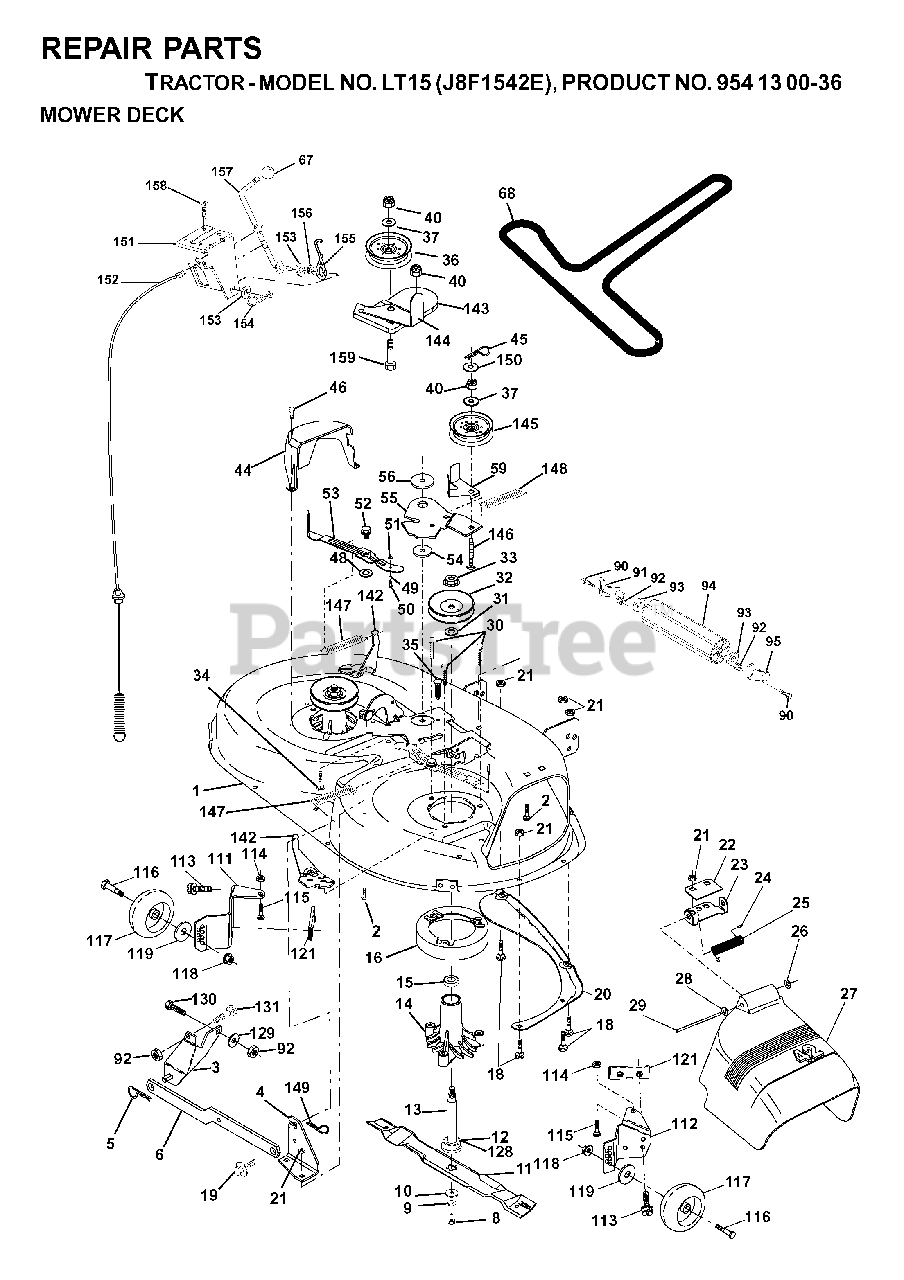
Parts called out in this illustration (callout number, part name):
1	42" DECK KIT
2	BOLT
3	BRKT ASM SWAY BAR
4	BRACKET SWAY BAR 42" DECK
5	RETAINER-SPRNG RB
6	REAR SUSP ARM
8	BLADE BOLT
9	LOCKWASHER
10	WASHER.BLADE
12	BEARING
13	SHAFT ASM VENT
14	HSG MANDREL
16	STRIPPER
18	BOLT
19	BOLT SHD 5/16-18
20	BAFFLE.VORTEX
21	LOCKNUT
22	STIFFENER BRACKET
23	DEFLECTOR BRACKET
24	CAP-SLEEVE LT
25	SPRING TORSION
26	NUT PUSH M
27	SHIELD DEFLECTOR
28	WASHER
29	ROD.HINGE
30	SCREW THDROL ROLLING WASHER HD
31	WASHER
32	PULLEY/MANDREL
33	NUT
34	BOLT
35	FASTENER.XMAS.TREE
36	FLAT IDLER PULLEY
40	LOCKNUT
44	GUARD MANDREL LH BLACK
45	RETAINER M
46	SCREW.1/4-20X5/8
49	ROLLER ASSY
50	BOLT
53	ARM
54	HARDENED WASHER
55	ARM IDLER 42" MOWER LT/YT
56	SPACER.RETAINER.MOWER
59	GUARD, BELT
67	KNOB T (3/8 HOLE)
90	BOLT
91	BRACKET LH (A)
92	NUT
94	NOSE ROLLER
95	BRACKET RH (B)
111	BRACKET WHEEL GAUGE LH 42" DK
112	BRACKET WHEEL GAUGE RH 42" DK
113	SCREW 5/16"
114	NUT
115	BOLT
117	WHEEL.GAUGE.STANDARD
118	LOCKNUT
119	WASHER
121	BRACKET.EXTRD.GWL
128	WASHER FELT
129	WASHER
130	BOLT
131	BOLT D
142	ARM SPRING BRAKE MOWER
143	BRACKET, ARM IDLER
144	KEEPER.BELT.42".CLUTCH.CABLE
145	PULLEY
146	BOLT, CARRIAGE IDLER
147	SPRING EXTENSION
148	IDLER RETURN SPRING
150	WASHER PM
151	BRACKET, CLUTCH CABLE
152	CLUTCH CABLE 42"
153	WASHER FLAT 3/8"
154	SPRING RETAINER
155	SPRING RETENTION LEVER
156	SPACER CLUTCH CABLE
157	ROD CLUTCH CABLE 3/8"
158	SCREW LT
159	BOLT
